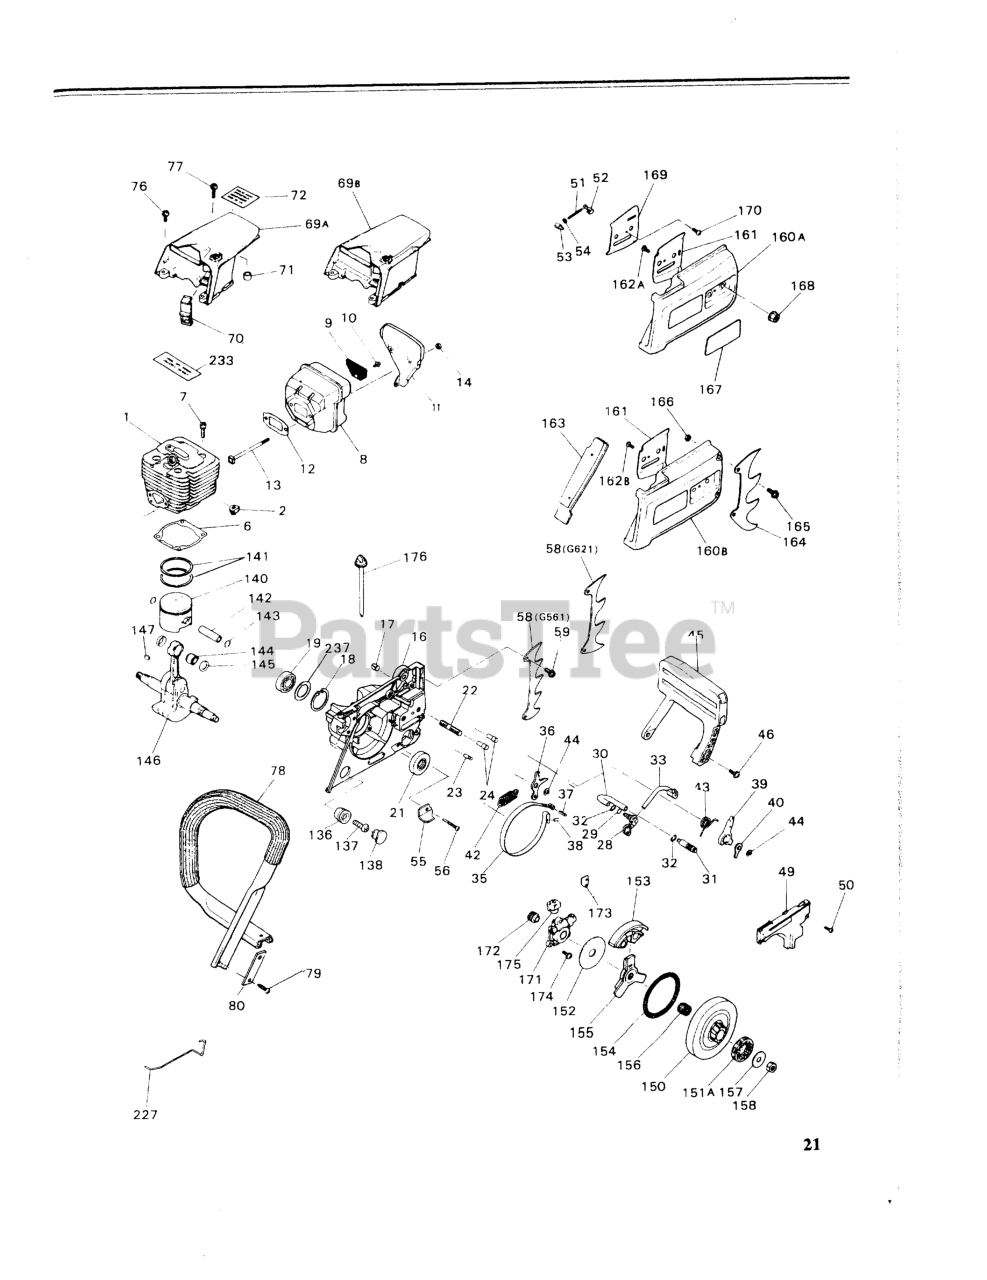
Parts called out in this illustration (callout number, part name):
1	CYLINDER
2	GROMMET
6	GASKET (USE -14211)
7	BOLT M5 x 20 (RPLS -12280)
9	ARRESTER, SPARK
10	SCREW, M4 X 8
12	GASKET
13	BOLT
16	CRANKCASE (USE -21101)
17	CRANKCASE (USE -21101)
18	RING, SNAP, M35 X 1.5
22	STUD (RPLS 0205-50825)
23	PIN
24	PIN
28	PIPE, OIL
31	WEIGHT
33	PIPE, OIL
35	BAND
36	ARM
38	PIN
39	LEVER, BRAKE (USE 2622-24210)
40	STOPPER (USE 2622-24500)
42	SPRING COMP
43	SPRING
44	RING, SNAP, M6
45	GUARD (USE 848-C90-54A4)
49	COVER, BRAKE (RPLS -24411)
50	SCREW, M5 x 14
51	ADJUST SCREW
52	STOPPER, ADJUS
53	NUT (A)
54	WASHER, M5 X .8
58	SPIKE BUMPER
59	SCREW
69B	COVER (G621AVS)
70	CAP
71	GROMMET (RPLS-31151)
76	SCREW,M5 X 14 (RPLS 1400-15510
77	SCREW, M5X20 (RPLS.1400-75510)
78	HANDLE L
79	SCREW (USE 848-825-1901)
80	PLATE (RPLS 2616-32180)
136	DAMPER (RPLS 2670-35110)
137	SCREW
138	CAP (RPLS -35180)
141	RING
142	PIN, PISTON
143	RING, SNAP
144	BEARING
145	WASHER (RPLS 1491-41510)
146	CRANKSHAFT (RPLS -42003)
147	KEY
150	DRUM, CLUTCH
151A	RIM SPROCKET, .325, 7-TOOTH
152	PLATE
153	CLUTCH ASSY (RPLS -51200)
154	SPRING (RPLS -51230)
155	CLUTCH ASSY (RPLS -51200)
156	BEARING
157	WASHER
158	NUT
160A	COVER, CHAIN (RPLS. -53002)
160B	CHAIN COVER
161	PLATE (OUT)
162A	SCREW, M4 x 10
162B	SCREW, M4 x 10
163	PROCTECTOR
164	BUMPER SPIKE
165	SCREW (REPLACES 2616-24320)
166	NUT (B)
168	NUT
169	PLATE (IN)
170	SCREW, M4 x 10
172	GEAR, WORM
173	GASKET, PUMP
174	SCREW, M5X20 (RPLS.1400-75510)
175	GROMMET (RPLS -55451)
176	SHAFT
227	ROD (RPLS 3356-82411)
237	RING
NI	OIL PIPE COMP
NI	BAND COMP
NI	COVER COMP (RPLS -31102)
NI	SHIM (REPLACES 848-870-G000)
NI	CLUTCH ASSY (RPLS -51200)
